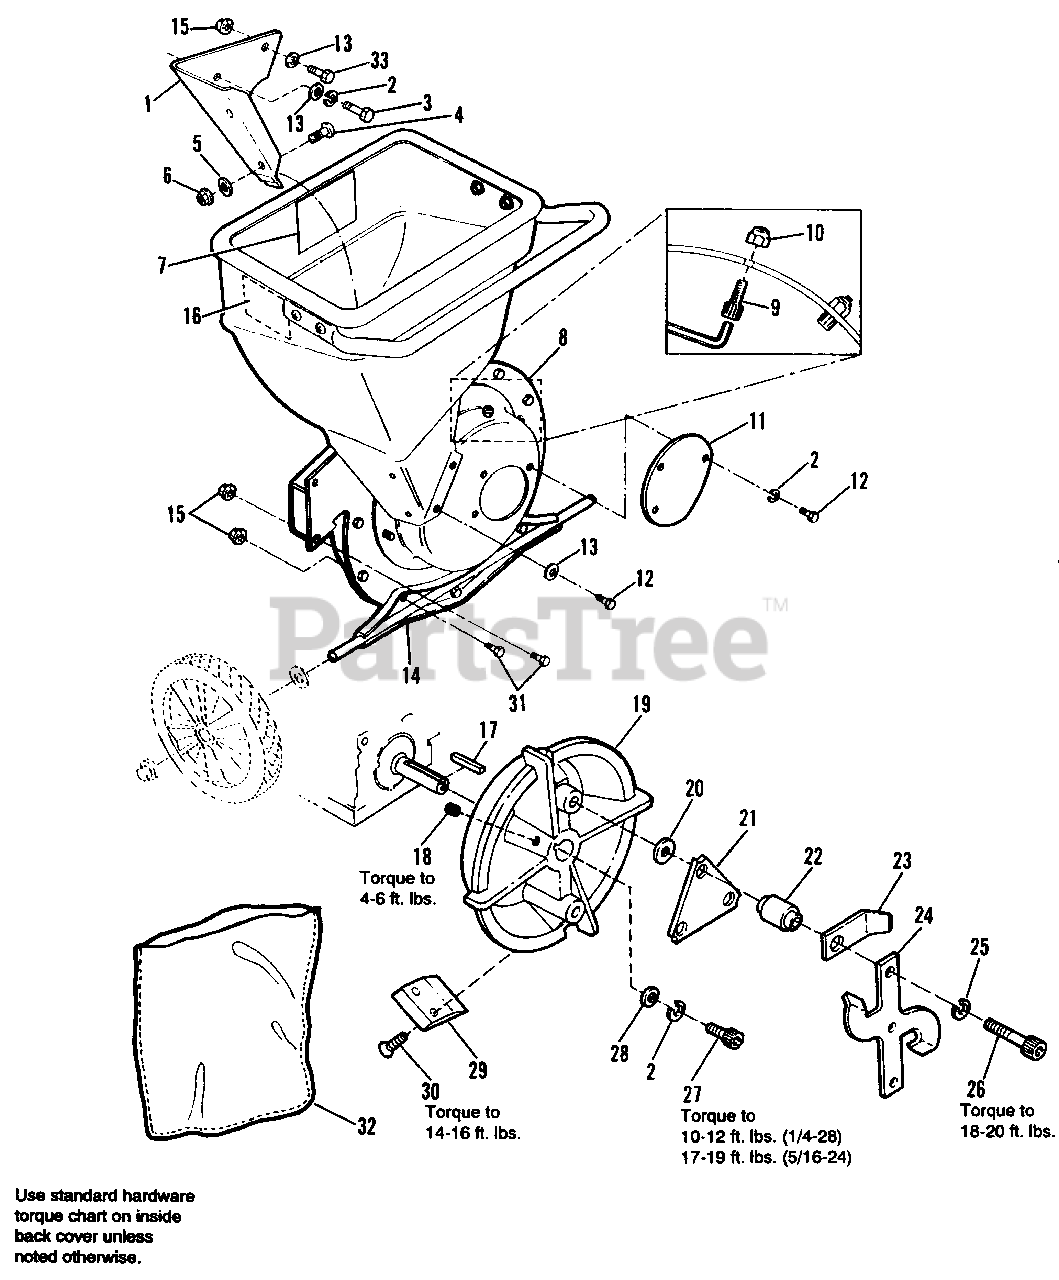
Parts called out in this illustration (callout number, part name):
1	HOPPER LINER
2	LOCKWASHER, 5/16 (Qty. 4 on Model 3/10, 5/10)
3	CAPSCREW, Hex Hd., 5/16-18 x 1, Gr.5
4	SCREW, Button Hd., Hex Socket, 1/4-20 x 3/4
5	WASHER, Flat, 1/4
6	NUT, 2-Way, 1/420
7	DECAL, Caution/Operate
8	BAFFLE PLATE ASSY.
9	CAPSCREW, Soc. Hd., 5/16-18 x 1/2
10	NUT, Nylock, 5/16-18
11	COVER, Rotor Housing
12	CAPSCREW, Hex Hd., 5/16-18 x 1/2
13	WASHER, Flat, 5/16
14	A x LE ASSY.
15	NUT, Whiz Lock, 5/16-18
16	DECAL, Danger
17	KEY, 3/16 x 1/4 x 1-7/8
18	SET SCREW, 1/4-20 x 3/8
20	WASHER, 3/8
21	HAMMER, Triangular
24	BOOSTER FAN
25	LOCKWASHER, 3/8
26	CAPSCREW, Hex, Socket Hd., w/Patch, 3/8-16 x 2 1/2
27	CAPSCREW, Hex, Socket Hd., w/Patch 5/1 6-24 x 1 (2/10 Only)
27	CAPSCREW, Hex, Socket Hd., w/Patch, 1/4-28 x 1 (3/10, 5/10 Only)
28	WASHER, 5/16 (2/10 Only)
28	WASHER, 1/4 (3/10, 5/10 Only)
30	SCREW, Machine, Socket Flat.Hd., 5/16-18 x 3/4
31	CAPSCREW, Hex Hd., 5/16-18 x 5/8
32	BAG, 24" x 36"
33	CAPSCREW, Hex Hd., 5/16-18 x 3/4, Gr.5
